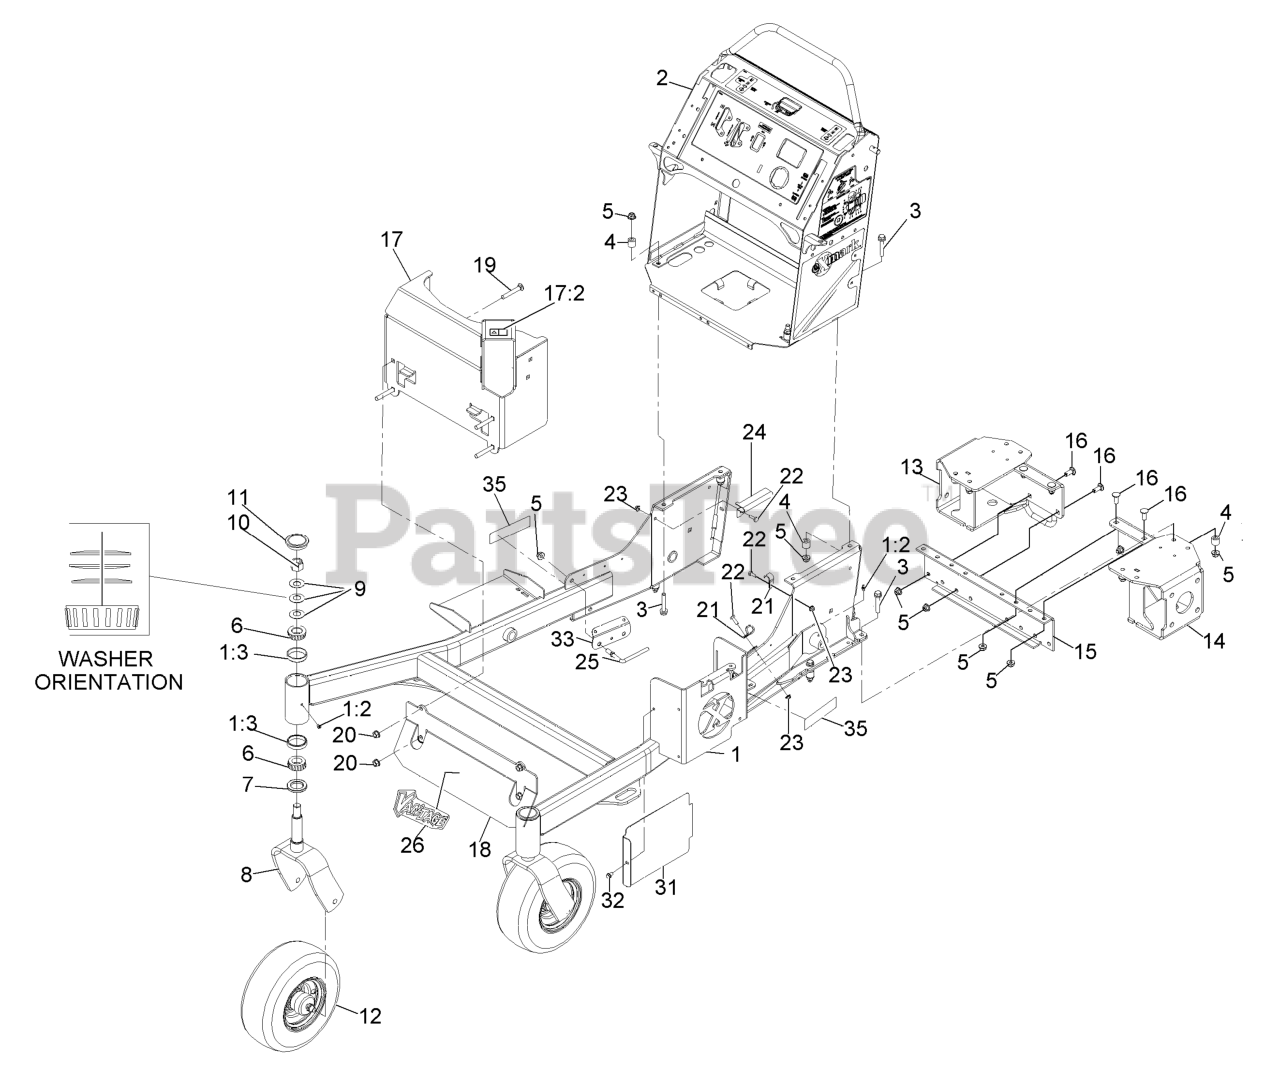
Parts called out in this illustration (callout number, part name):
1	FRONT FRAME ASM
1:2	FITTING-GREASE
2	CONTROL TOWER ASM-EFI
3	SCREW-HHF
5	NUT-HF, NI
6	Cone-Bearing Tapered Roller
7	SEAL-GREASE
8	FORK-CASTER
9	WASHER-BELLVILLE
10	NUT-LOCK, NI
11	CAP-GREASE
12	WHEEL/TIRE AND BEARING AS
13	RH MOTOR MOUNT ASM
14	LH MOTOR MOUNT ASM
15	MOUNT-MOTOR, CENTER
16	SCREW-CARR
17:2	DECAL-WARNING
18	PANEL-GUARD
19	SCREW-CARR
21	CLAMP-CABLE
22	SCREW-HH
24	BRACKET-HOSE, FUEL
25	GUIDE-HOSE, SUPPORT
26	DECAL-VANTAGE LOGO
31	SHIELD-HEAT, TALL
32	SCREW-HWH
33	GUARD-HOSE
35	DECAL-S-SERIES
